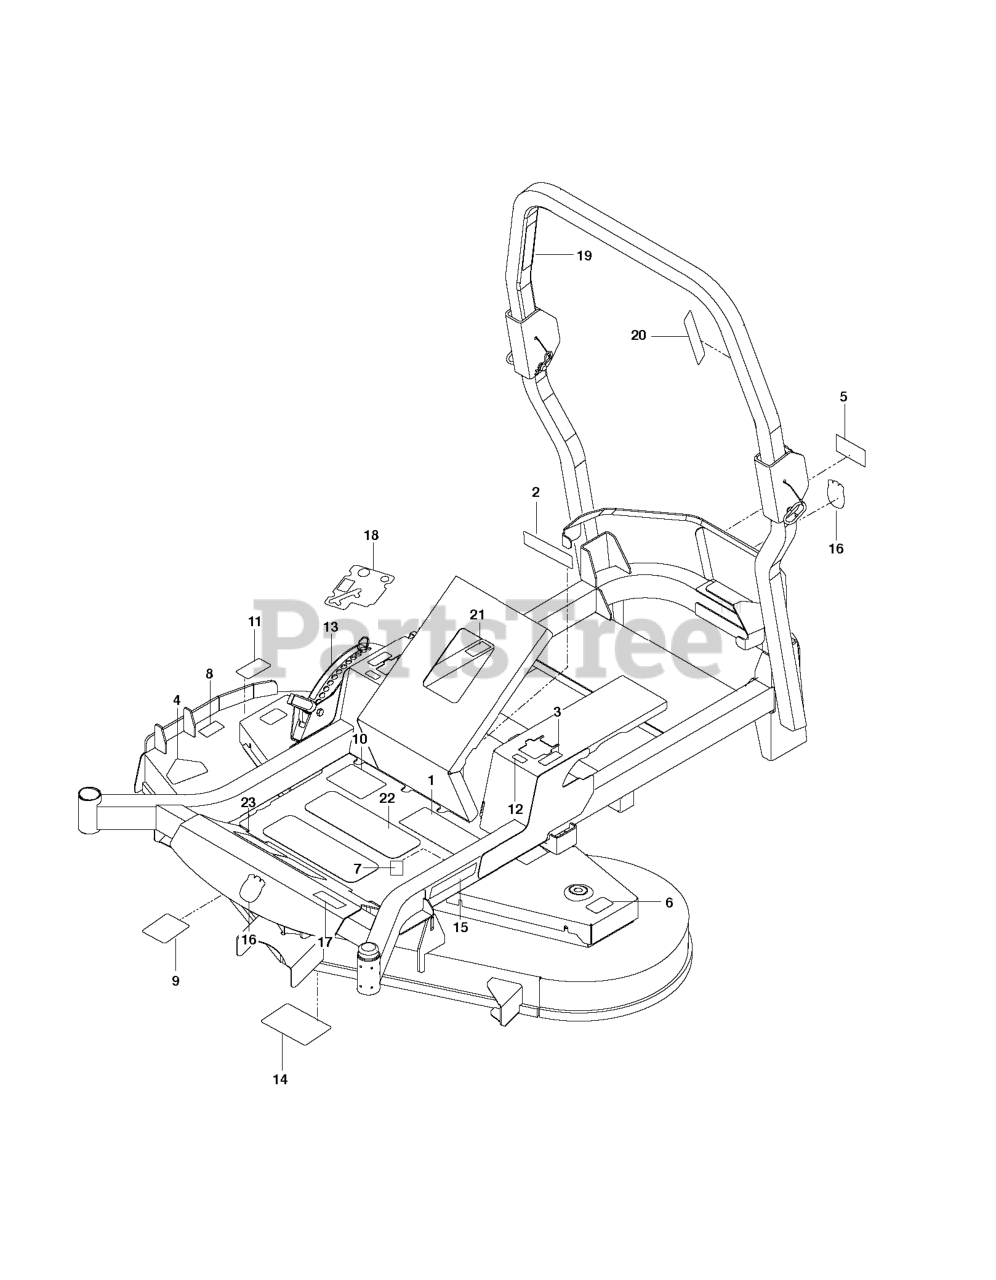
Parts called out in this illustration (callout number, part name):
1	DECAL, WARNING
2	EURO DECAL-BATTERY WARNIN6
3	DECAL, MOTION CONTROL
4	DECAL, CPSC
5	DECAL, BELT DRIVE
6	DECAL.DECK.6MIL.EURO.NOSTEP
7	DECAL.80.DBA.AUSTRALIA
8	DECAL, EURO SEVERING
9	DECAL, BELT ROUTING
10	DECAL, WARNING
11	DECAL.DECK.6MIL./DEF.SHLD.WARN
12	DECAL, F.S.T.
13	DECAL, HEIGHT ADJUST
14	DECAL, SERVICE
15	RP.DECAL.BADGE.170MM.TEXTLOGO
16	DECAL.AUGER.HUSQ.CROWN.SNOW
17	DECAL.MZ52
19	DECAL, ROPS, WARNING
21	DECAL, ECM, AUSTRALIA
22	ANTI-SKID PAD
